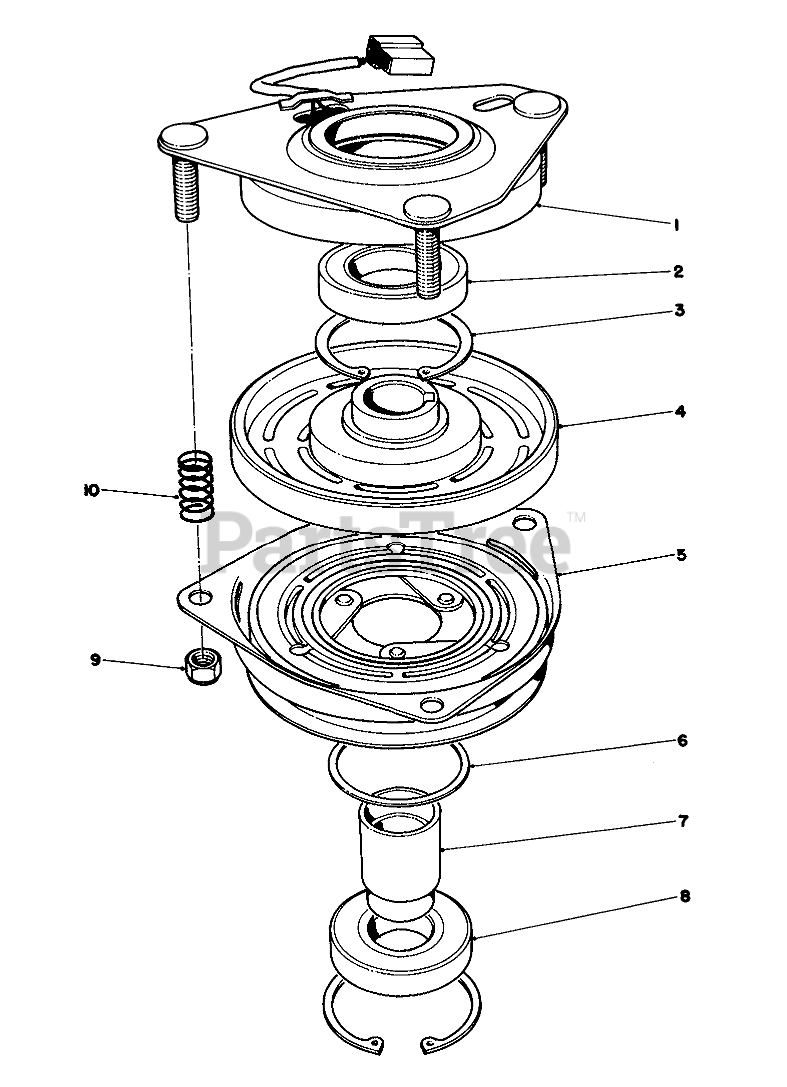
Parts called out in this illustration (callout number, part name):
1	Field Assembly (Incl. Ref. #2 & 3)
2	BEARING-FIELD
3	RING-RETAINING
4	Field Coil, Rotor & Bearing Assembly (Incl. Ref. #1)
5	Armature & Pulley Assembly (Incl. Ref. #3, 6, 7 & 8)
6	SPACER-BEARING, PULLEY
7	COLLAR-BEARING
8	BEARING-PULLEY
9	NUT-LOCK
10	SPRING
